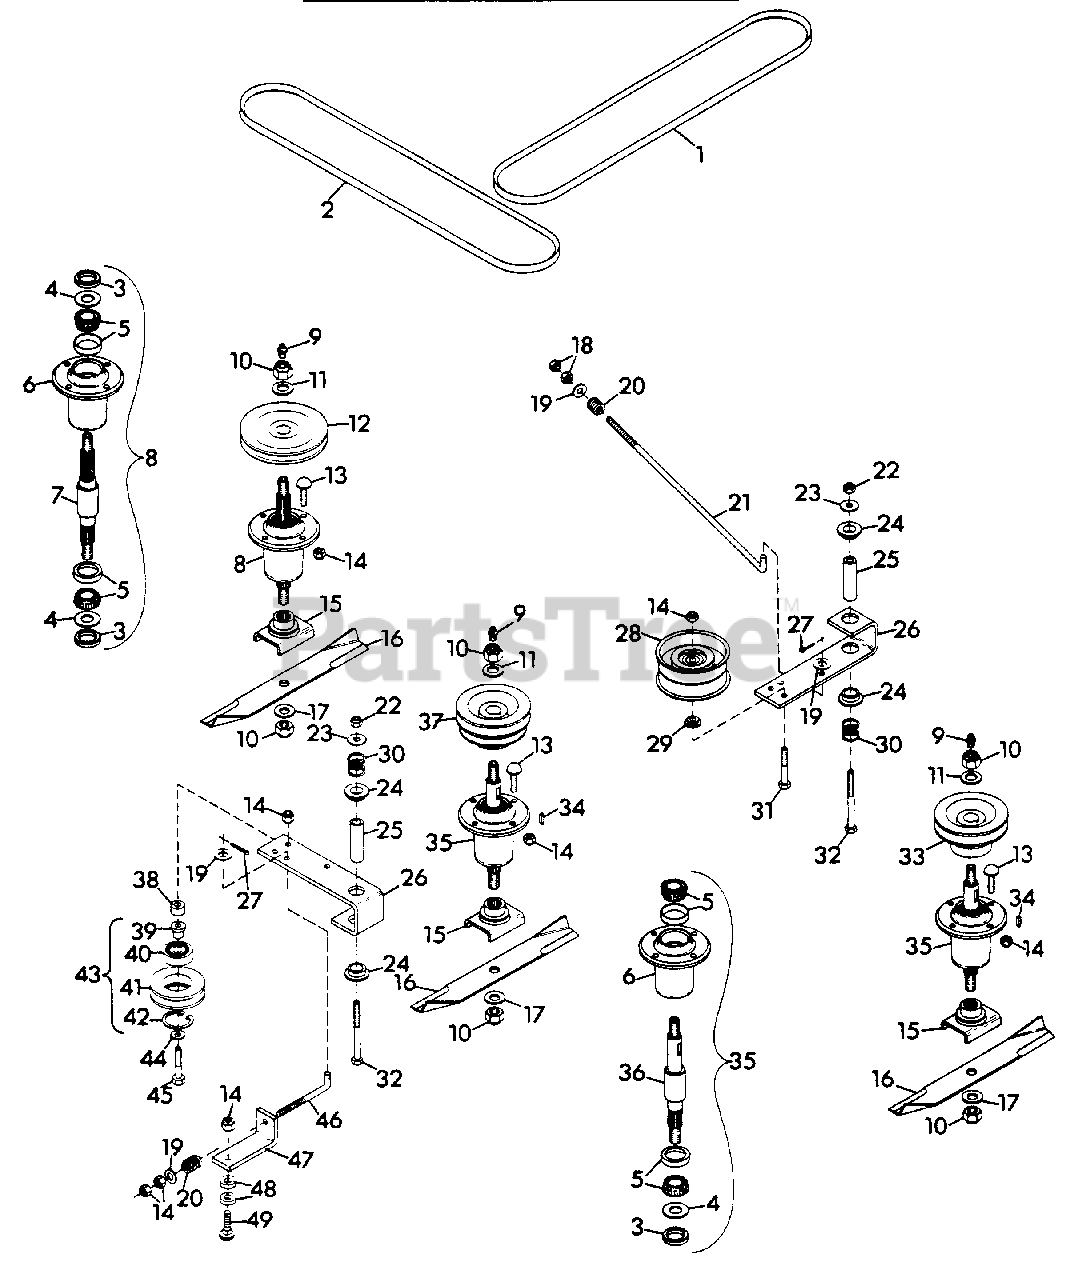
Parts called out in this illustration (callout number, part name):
1	BELT, V
2	BELT, V
3	SEAL, STEEL(IN 34605)
3	SEAL, STEEL(IN 21306)
4	WASHER, FLAT .975X1.970X.030(IN 34605)
4	WASHER, FLAT .975X1.970X.030(IN 21306)
5	ASSEMBLY, BEARING
6	HOUSING, BEARING
7	SHAFT, SPINDLE
8	ASSEMBLY, SPINDLE
9	FITTING, LUBE 1/8
10	NUT, LOCK 5/8-11
11	WASHER, FLAT .687X1.312X.122
12	PULLEY
13	BOLT, 3/8-16X1.375 RD HD SQ NK
14	NUT, LOCK 3/8-16
15	WELDMENT, BLADE CRADLE
16	BLADE
17	WASHER, FLAT .656X1.312X.095
18	NUT, HEX 3/8-24
19	WASHER, FLAT .406X.812X.065
20	SPRING, COMP. 1X.78
21	ROD, IDLER
22	NUT, LOCK 1/2-13
23	WASHER, FLAT .531X1.250X.100
24	BUSHING, NYLON .76X1X.6 FIG.
25	SPACER
26	ARM, IDLER PIVOT
27	PIN, COTTER .09X.75
28	PULLEY, IDLER
29	BUSHING
30	SPRING, COMP. 1X.80X36 LB/N
31	BOLT, HEX 3/8-16X2.25
32	BOLT, HEX 1/2-13X3.25
33	SHEAVE, SPINDLE
34	KEY, WOODRUFF .250X1 HARD #15
35	ASSEMBLY, SPINDLE
36	SHAFT, SPINDLE
37	SHEAVE, SPINDLE
38	SPACER, IDLER .406X.625X.48
39	BUSHING, IDLER SHEAVE
40	BEARING, BALL
41	SHEAVE, IDLER
42	RING, RETAINING
43	ASSEMBLY, IDLER SHEAVE
44	WASHER, FLAT .375X1.125X.065
45	BOLT, HEX 3/8-16X2.00
46	ROD, IDLER
47	BRACKET, BELT TENSIONER
48	SPACER
49	BOLT, 3/8-16X1.75 RD HD SQ NK
